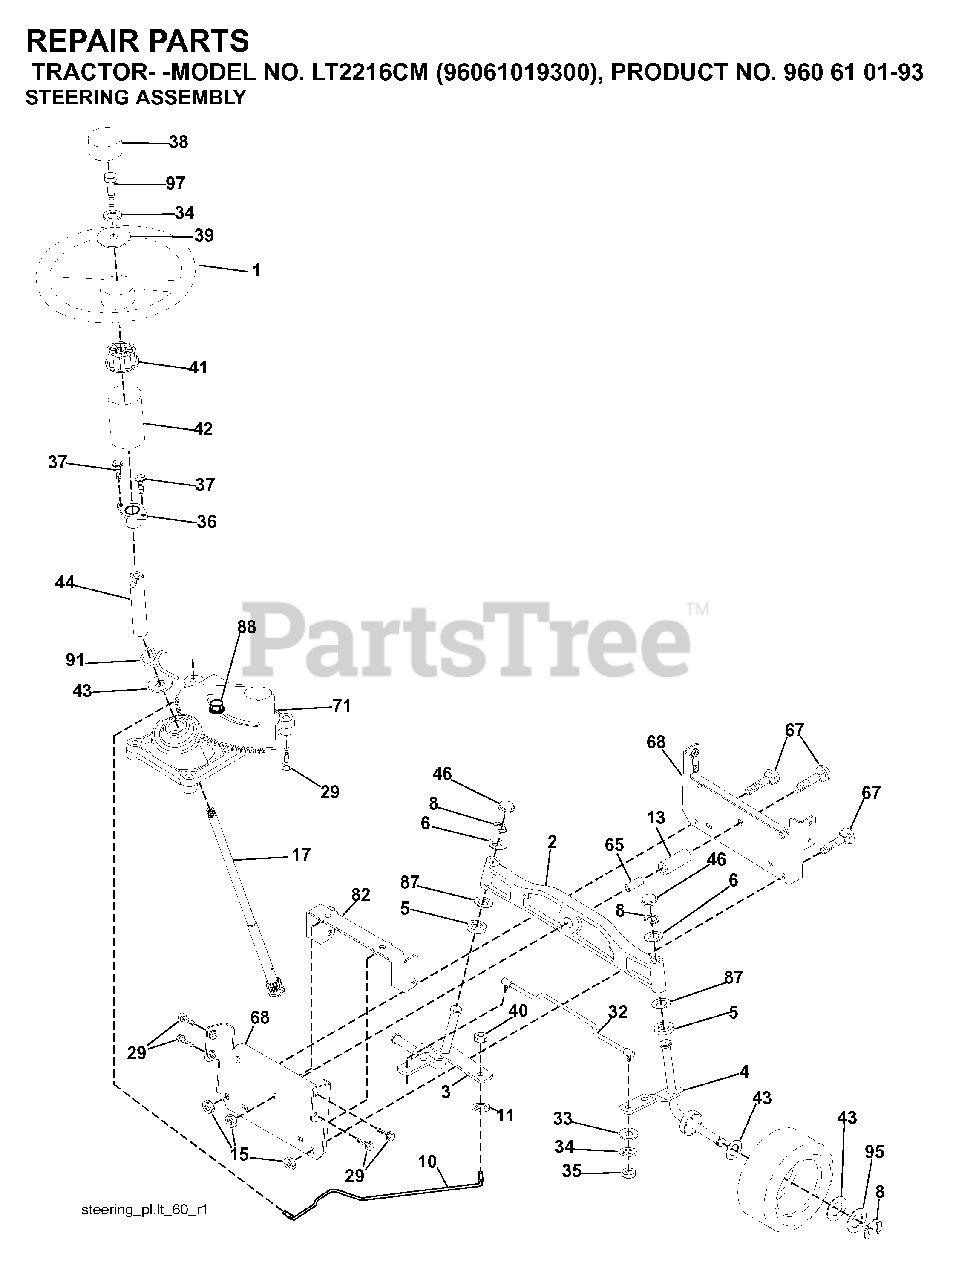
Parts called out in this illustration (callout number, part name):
1	WHEEL.STEERING.PREM.2.BLK
2	AXLE ASSY FRONT
3	SPINDLE.ASM.LH.15"TIRES
4	SPINDLE.ASM.RH.15"TIRES
8	RING CLIP
10	DRAGLINK.15".TIRES.2001
11	WASHER, LOCK 3/8
13	TUBE, PIVOT AXLE
15	NUT
17	SHAFT STEERING SPLINE
29	SCREW, 3/8-16X3/4
32	ROD.ASM.TIE.BALL.JOINT.NOVAN
33	WASHER M
34	LOCKWASHER
35	NUT, CROWNLOCK
36	BUSHING, STEERING
38	INSERT.CAP.STRG.WH.BLACK
39	WASHER.11/32
40	NUT CROWNLOCK 3/8-24
41	ADAPTER, WHEEL STNG..
42	BOOT.STEERING.SHAFT.BLACK
44	SHAFT.EXTEN.STRG.SPLINE
46	CAP.SPINDLE
65	SPACER BRACE AXLE
67	BOLT CARRIAGE
68	BRACE.AXLE.15"TIRES
71	STEERING ASM
82	BRACKET.SUSP.CHASSIS.FRONT.15
87	WASHER, FLAT .781 X 1 1/2"
88	BOLT, SHOULDER 7/16-20
91	CLIP.STEERING
95	WASHER.HARDENED
